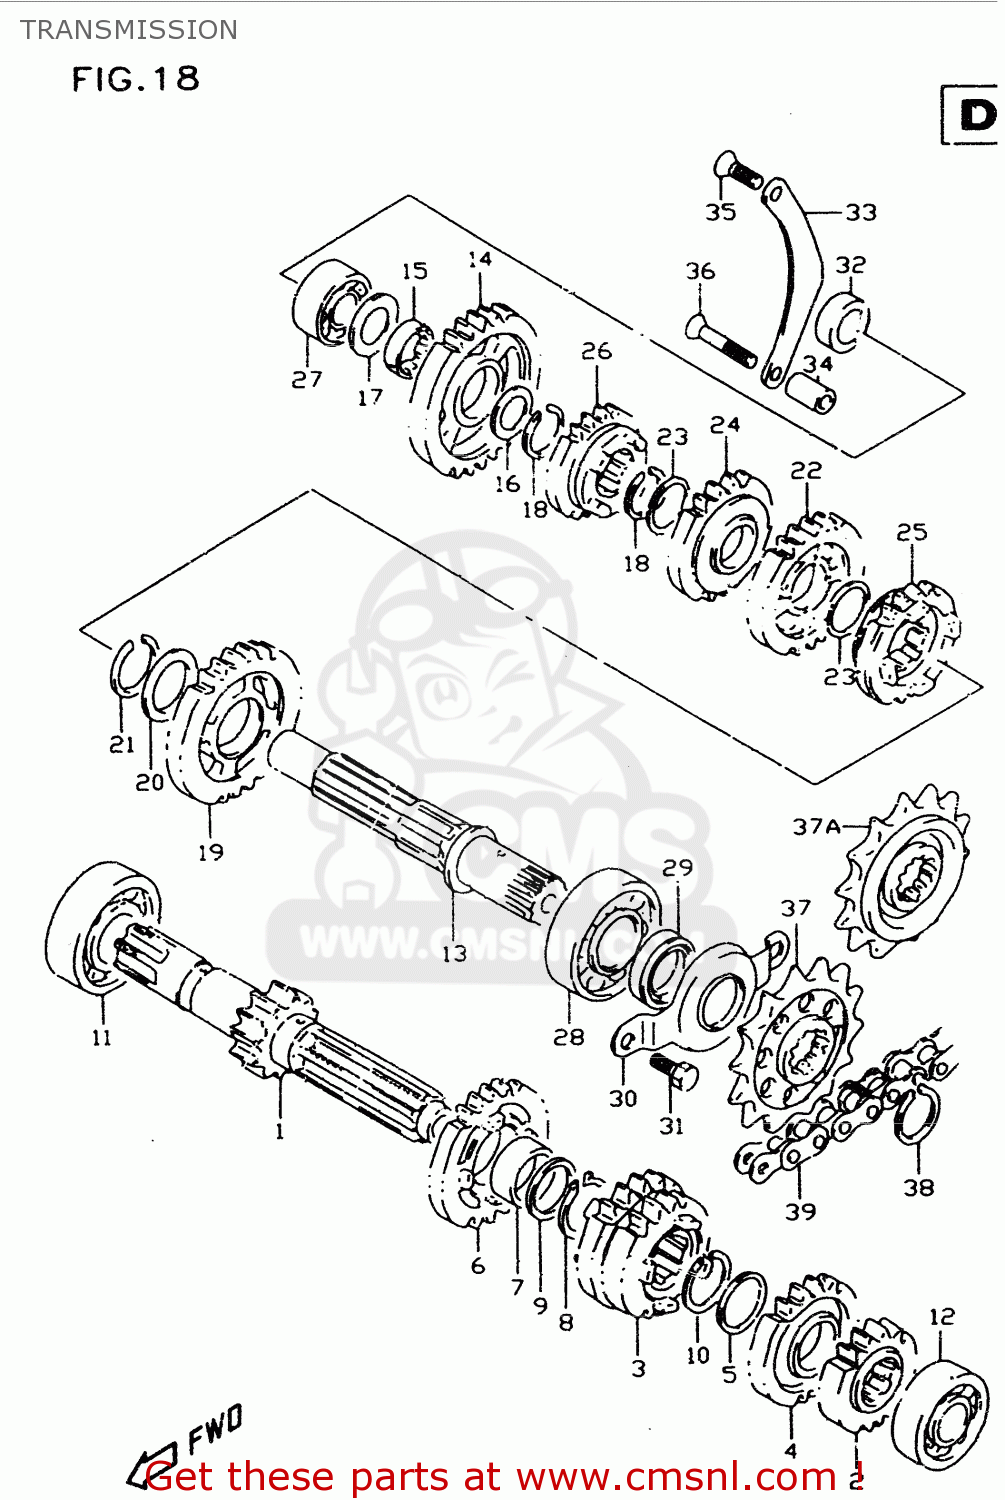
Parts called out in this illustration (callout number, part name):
1	SHAFT,COUNTER(NT:12)
2	GEAR,2ND DRIVE
3	GEAR,3RD & 4TH DRIVE(NT:18/18)
4	GEAR,5TH DRIVE(NT:21)
5	WASHER
6	GEAR,6TH DRIVE(NT:23)
7	BUSH(22X26X9)
8	CIRCLIP
9	WASHER,THRUST
10	CIRCLIP
11	BEARING 20X52X15
12	BEARING
13	SHAFT,DRIVE
14	GEAR,1ST DRIVEN(NT:30)
15	BUSH,1ST DRIVEN GEAR
16	WASHER
17	WASHER,THRUST
18	CIRCLIP
19	GEAR,2ND DRIVEN(NT:26)
20	WASHER
21	CIRCLIP
22	GEAR,3RD DRIVEN(NT:24)
23	SHIM
24	GEAR,4TH DRIVEN(NT:20)
25	GEAR,5TH DRIVEN(NT:20)
26	GEAR,6TH DRIVEN(NT:19)
27	BEARING(17X40X17.5)
28	BEARING(22X56X16)
29	SEAL,OIL(22X34X7)
30	RETAINER,DRIVE SHAFT OIL SEAL
31	BOLT
32	SPACER(17X25X10.5)
33	RETAINER,KICK IDLE GEAR
34	SPACER(6.5X12X21)
35	SCREW ,6X16
36	SCREW
37	SPROCKET(NT:15)
37A	SPROCKET,ENGINE(NT15)
38	CIRCLIP
39	CHAIN(DID520VM,108LE)
